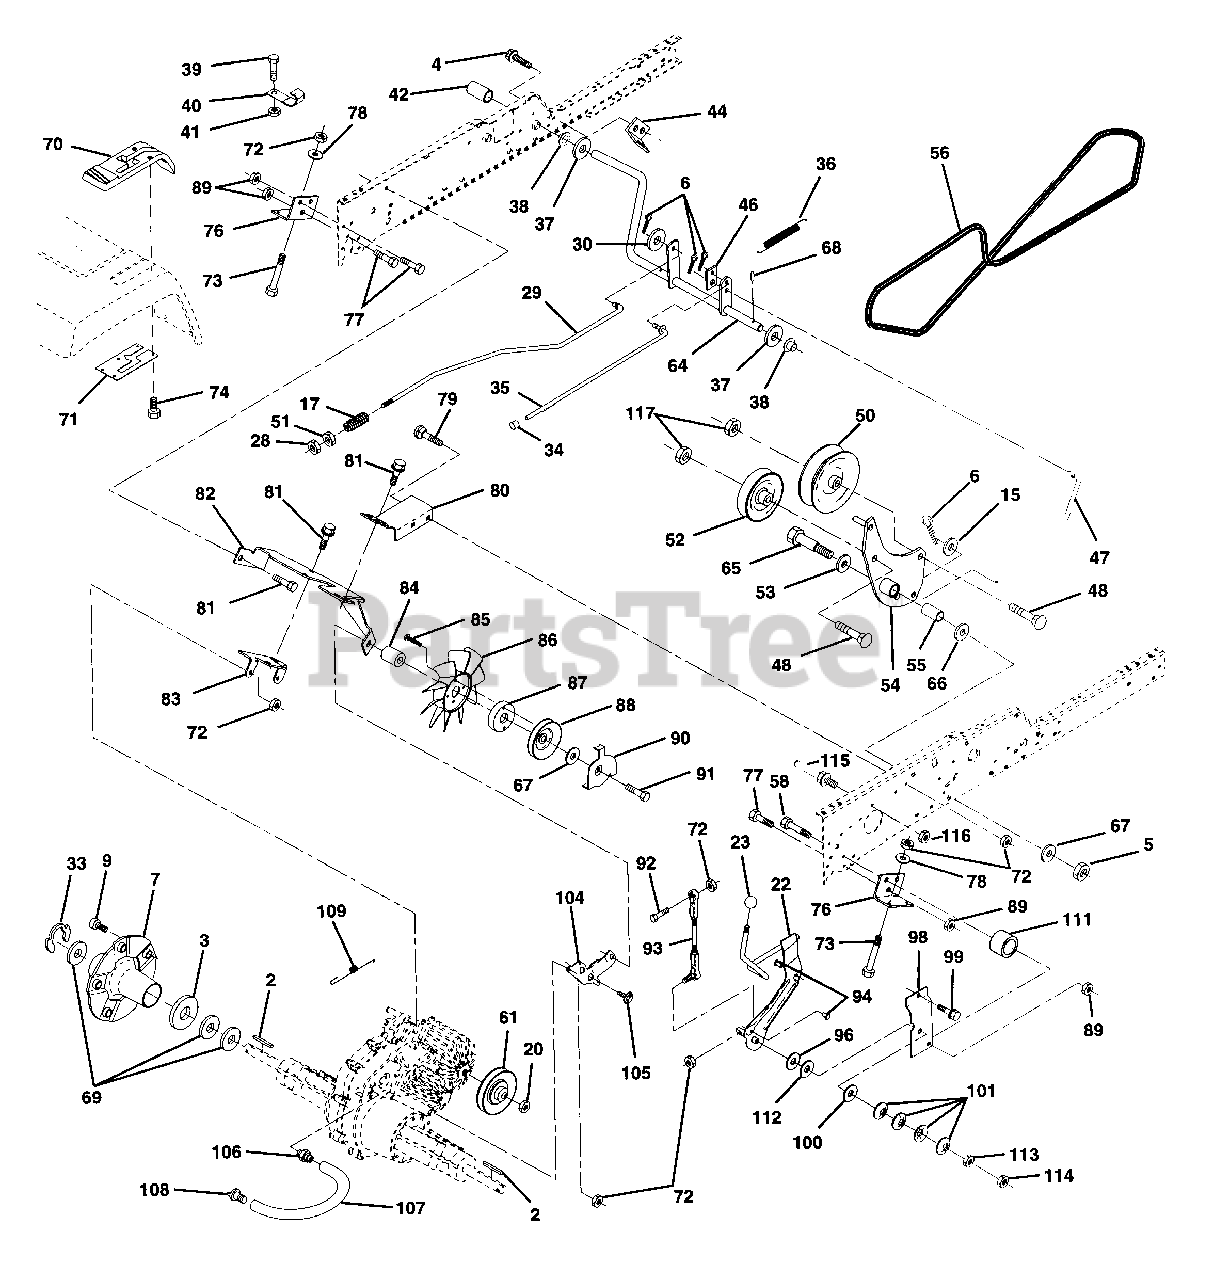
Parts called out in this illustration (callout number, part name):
2	Key 1/4 x 2.5
3	Washer Thrust Axle Harden
5	Nut Crownlock 3/8-16
6	Pin Cotter 1/8 x 3/4
7	Wheel Hub Asm.
15	Washer 13/32 x 13/16 x 16 Ga.
17	Spring Rod Brake
20	Nut Hex Jam Toplock 1/2-20
22	Shaft Arm Asm
28	Nut, Hex Jam 3/8-16
30	Washer 13/32 x 1 x 16Ga
32	Nut Hex 7/16-14
34	Cap Plunger
35	Rod Parking Brake
36	Spring Drive Ground
37	Washer 25/32 x 1-1/4 x 16 Ga.
39	Screw Fin #10-24 x 1
40	Actuator Interlock Switch
41	Nut Lock #10-24
42	Cover Pedal
43	Bolt Hex Head 1/4-20 x 3/4
44	Bracket Interlock
45	Nut Lock W/Insert 1/4-20
46	Retainer Spring
47	Clutch Rod
48	Bolt Carriage 3/8-16 x 1-3/4 Gr. 5
49	Washer 13/32 x 7/8 x 13 Ga
50	Pulley Idler Flat
51	Nut Lock Hex 3/8-16
52	Pulley Idler Grooved
53	Washer Hartdened
54	Clutch Arm Asm
55	Bearing, idler
58	Bolt Fin Hex 7/16-14 x 1-1/2
61	Pulley Transaxle
64	Shaft Asm Brake Parking Clutch
65	Bolt Shoulder
66	Washer Hardened
67	Washer 13/32 x 13/16 x 12 Ga
70	Console Hydro Fender
71	Plate Console Shift
72	Locknut Hex W/Washer Insert
73	Bolt Fin Hex 5/16-18 x 3
74	Screw, Hex Wsh Hi-Lo 1/4-1/2
75	Nut Lock Hex 7/16
76	Bracket Transaxle
77	Bolt Fin Hex 7/16-14 x 1
78	Washer 11/32 x 3/4 x 12 Ga.
79	Bolt Carriage 5/1 6-18 x 5/8
80	Bracket Torque RH
81	Screw Thdrol 3/8-16 x 3/4
82	Bracket Mount Torque/Fan
83	Strap Torque Mid
85	Screw #10-24 x 1-1/4
86	Fan 7" Hydro
87	Adapter Fan
88	Pulley Idler
89	Nut, Crownlock 7/16-14
90	Keeper Belt
91	Screw Thdrol 3/8-16 x 2-3/4
92	Bolt Fin Hex 5/16-18 x 1.75
93	Link Shift Asm
94	Fastner Christmas Tree
95	Screw Set 5/16-18 x 1.75
96	Washer Nickel Plated
97	Bearing Trust
98	Bracket Shift
99	Screw Thdrol 3/8-16 x 1-1/2
100	Washer Compression
101	Washer Bellville
102	Nut Hex Nylok
103	Nut Hex Jam 5/16-18
104	Bracket Idler
105	Screw Tap 1/4-20 x 1/2
106	O-Ring Asm. Hydro Gear
107	Line Fuel Hydro
108	Cap Vent
109	Spring Return Brake
115	Keeper Belt Gnd Dr.
116	Nut Lock Hex Flange 5/16-18
